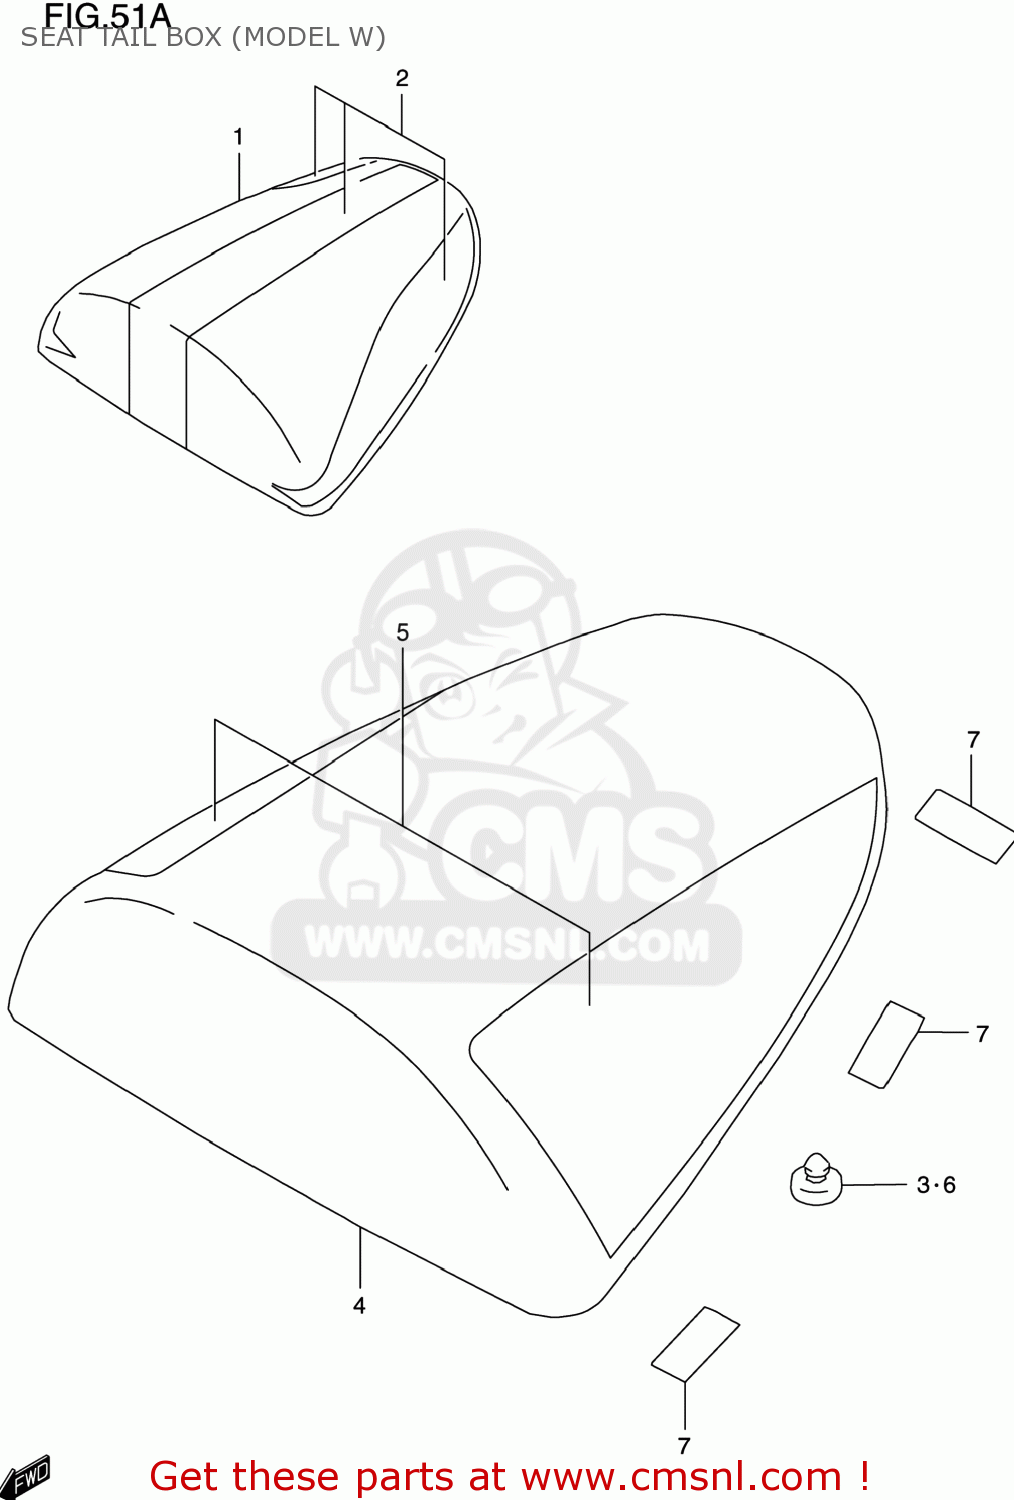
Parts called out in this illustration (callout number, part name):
1	BOX ASSY,SEAT TAIL(BLUE)
2	TAPE SET,BOX SEAT TAIL(WHITE)
3	CUSHION(11.5X22X20)
4	BOX ASSY,SEAT TAIL(BLACK)
5	TAPE SET,BOX SEAT TAIL
6	CUSHION(11.5X22X20)
7	PROTECTOR SET,SEAT TAIL BOX
